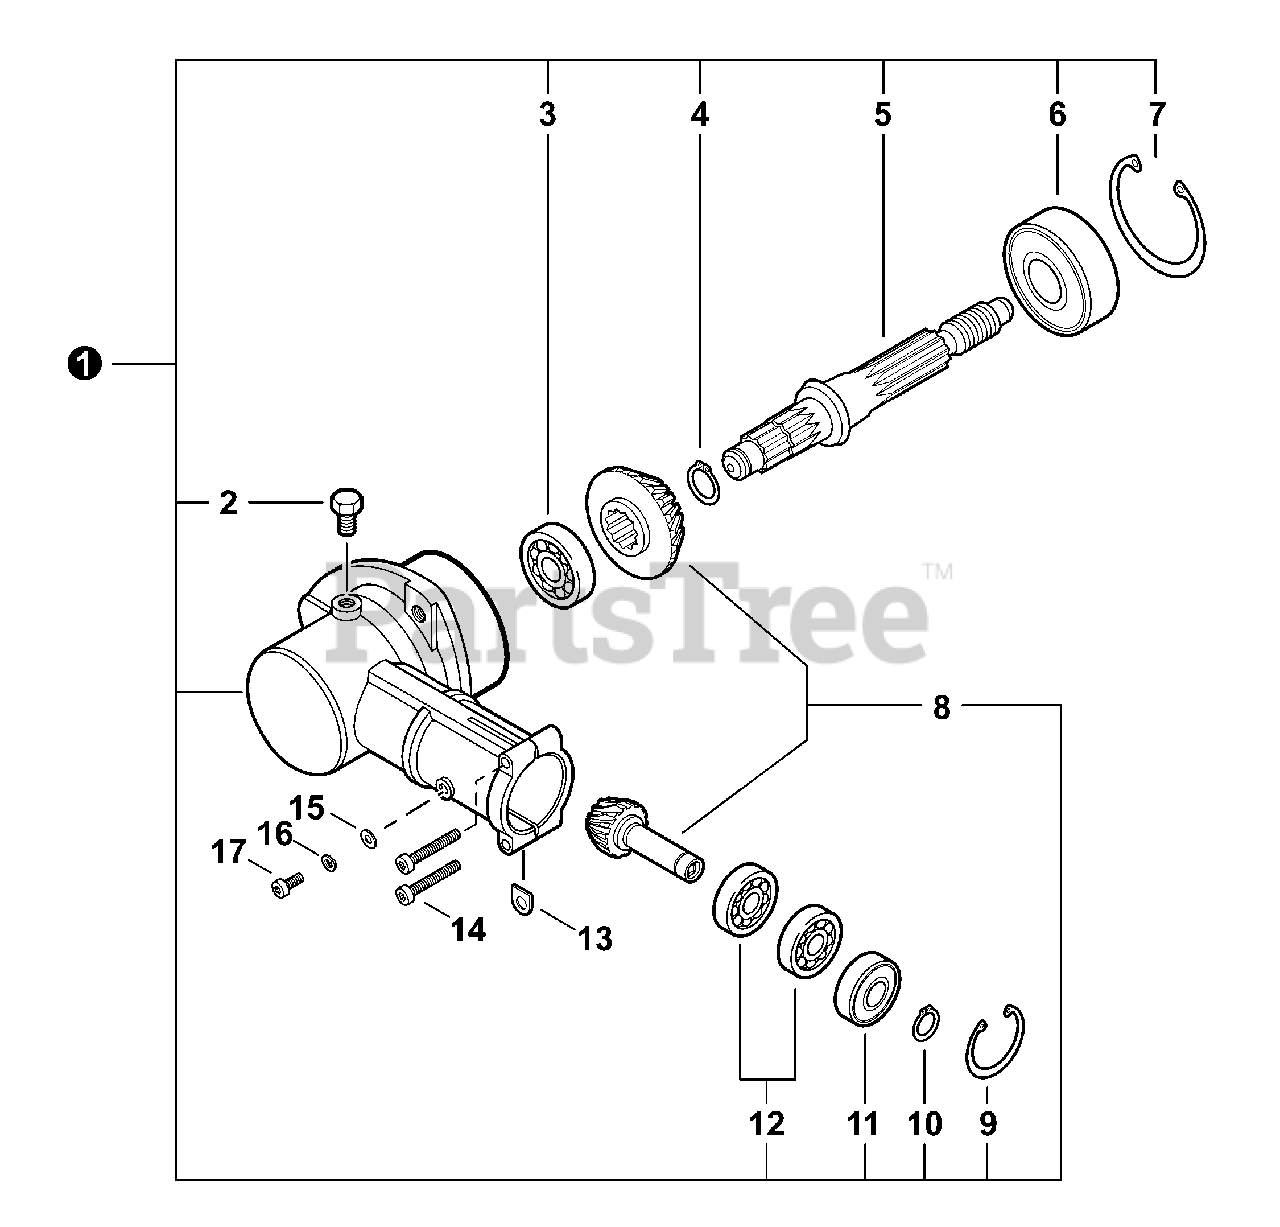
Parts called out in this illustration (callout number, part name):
1	GEAR CASE ASSY
2	BOLT M8×8
3	BEARING, BALL
4	RING, SNAP Ø12
5	SHAFT, GEAR
6	BEARING, BALL 6302
7	RING, SNAP Ø42
8	GEAR, BEVEL
9	RING, SNAP Ø22
10	RING, SNAP Ø10
11	BEARING, BALL 6900Z
12	BEARING, BALL 6900
14	BOLT, TORX 5×25
15	WASHER, FLAT 5.5×10×0.8
16	WASHER, SPRING 5
17	BOLT, TORX 5×10
